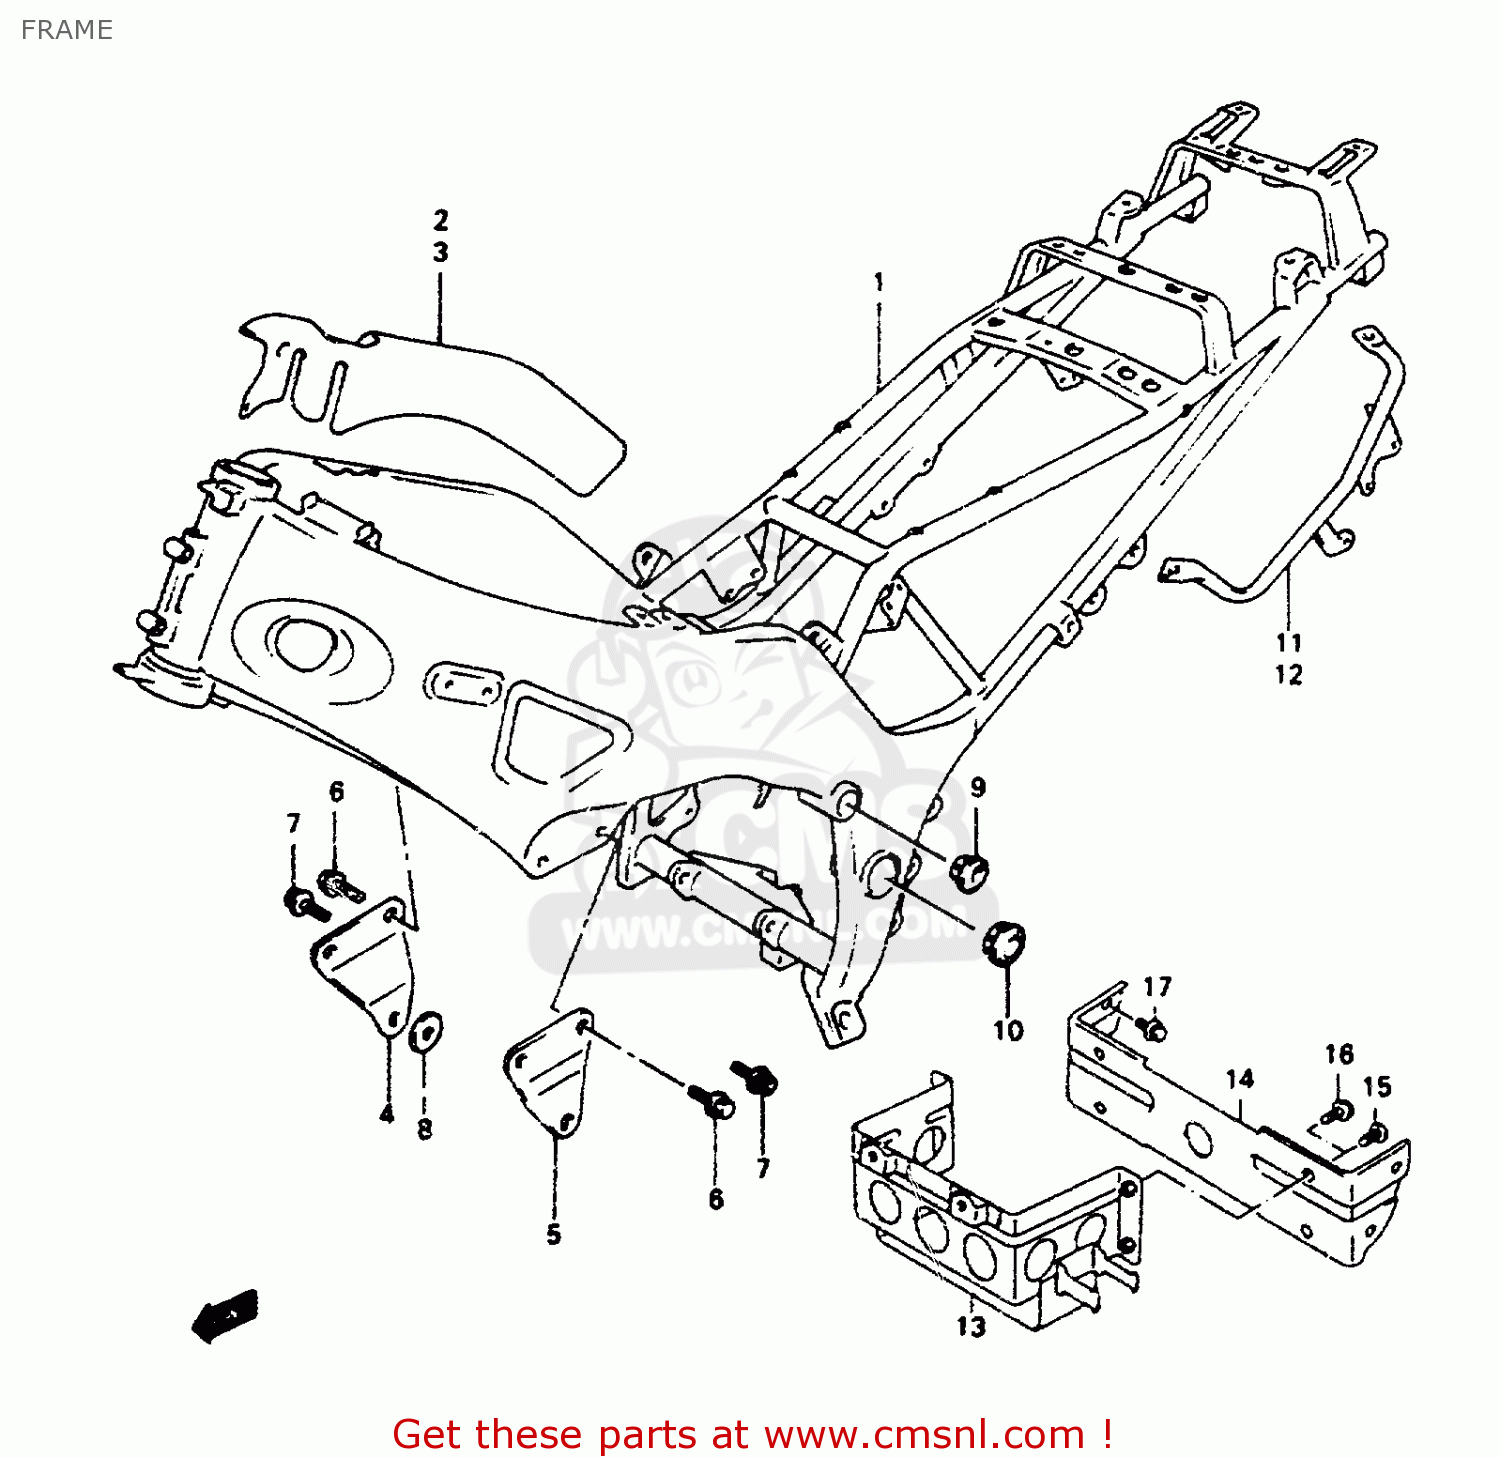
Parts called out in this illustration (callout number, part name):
1	FRAME (RED)
2	SHIELD,FRAME HEAT,RIGHT
3	SHIELD,FRAME HEAT,LEFT
4	PLATE,ENGINE MOUNT,R
5	PLATE,ENGINE MOUNT,L
6	BOLT
7	BOLT
8	WASHER (10.5X38X1.6)
9	CAP,FRAME BOSS,L
10	CAP,FRAME PIVOT
11	GRIP,RR,R
12	GRIP,RR,L
13	HOLDER,BATTERY
14	BRACKET,BATTERY HOLDER
15	SCREW 6X12
16	BOLT
17	BOLT
